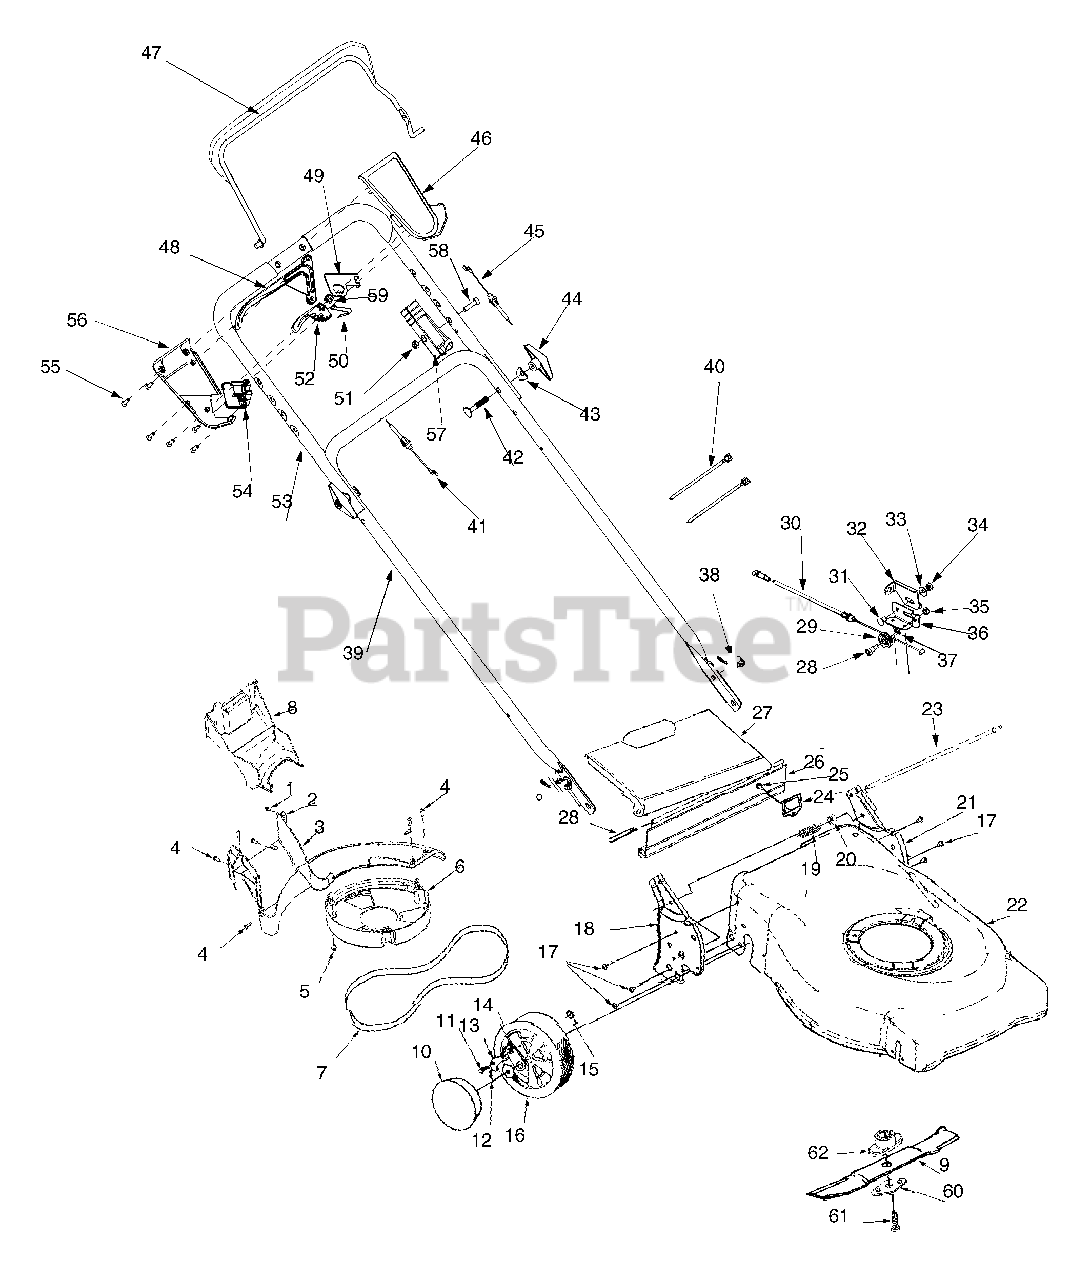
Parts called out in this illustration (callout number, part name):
1	Screw Mach. B Tapp
2	U-Nut
4	Screw HL 12-24
5	Screw Tap 1/4-20
6	Belt Cover
7	Belt
8	Mulch Plug
9	21" Mulching Blade w/Star
10	Hub Cap
11	Shldr. Scr. .340x.285
12	Spring, Ratchet
13	Pawl R.H.
14	Pawl Plate
15	Weld Top L. 1/4-20
16	Wheel Assembly
17	Screw AB 1/4-20
20	Spacer .385 I.D.
26	Rear Flap 17.77 Lg.
29	Roller Cable
30	6-Speed Cable
31	Carriage Screw 1/4-20 x .50
34	Hex Nut 1/4-28
35	Hex Nut 1/4-20
38	Cotter Pin
40	Cable Tie
41	Drive Cable
42	Cr.Hd. Bolt 5 / 16-18 x 2" Lg.
43	Saddle Washer .320 ID x .830 OD
45	Control Cable
46	Upper Control Handle
47	Control Handle Ass'y
48	Control Lever
49	6-Speed Rack Cable Bracket
50	Shift Lever Spring
51	Top Lock Nut
52	6-Speed Shift Lever
54	Cable Mounting Cap
55	C-Sunk Tap Screw #10-x.75 Lg
56	Lower Control Housing
57	Control Housing
58	Oval C Sunk Screw
59	Gear Insert
60	Blade Bell Support
61	Hex Bolt 3/8-24 x 2.5 Lg.
62	Blade Adaptor Kit w/Star
